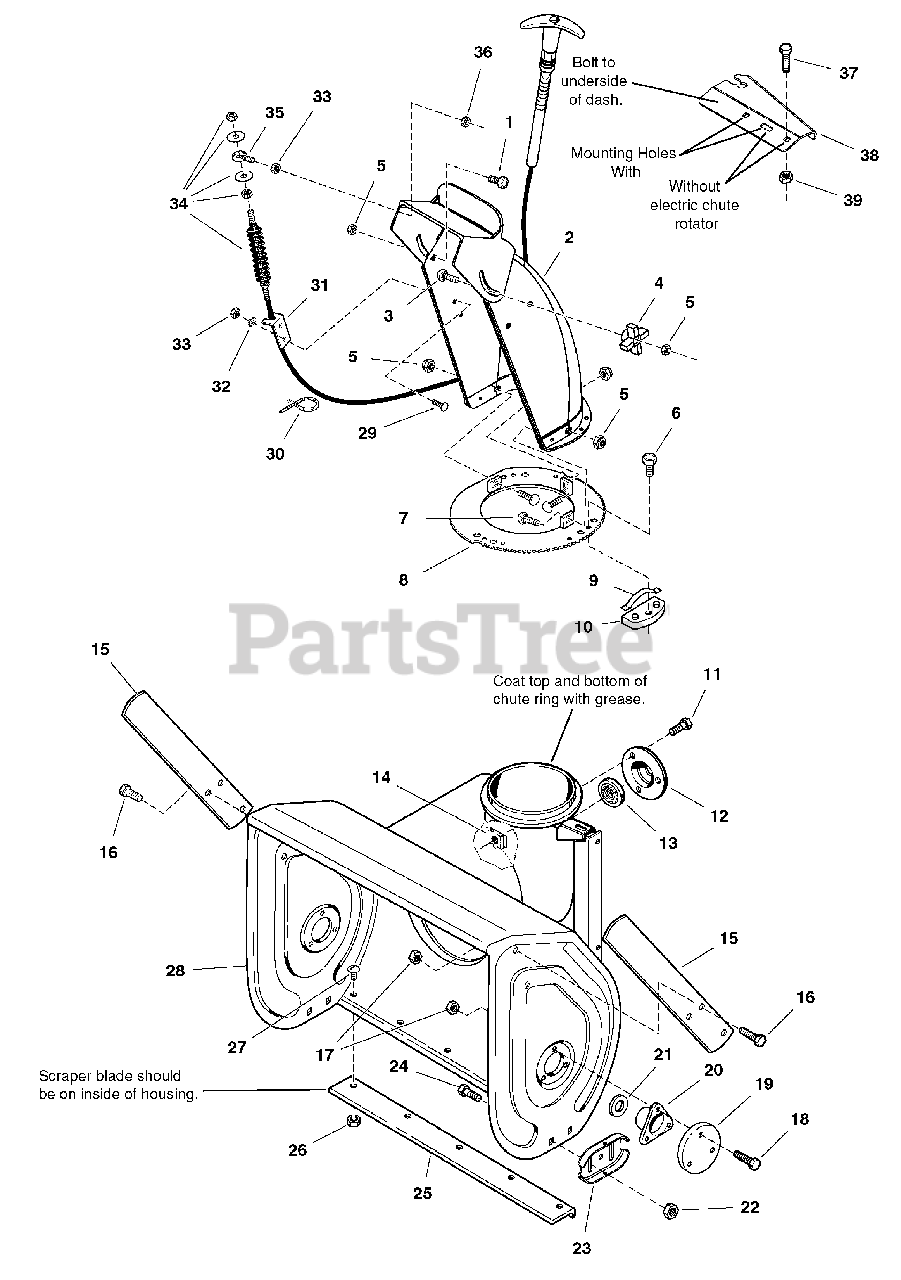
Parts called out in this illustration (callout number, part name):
1	CAPSCREW, Hex Head, 5/16-18 x 3/4 G5
2	CHUTE AND DEFLECTOR ASSEMBLY, w/Remote
2	CHUTE AND DEFLECTOR ASSEMBLY, Manual
3	BOLT, Carriage, Short Neck, 5/16-18 x 1
4	KNOB, Internal Thread, 5/16 (See Only 986714, 986717)
5	NUT, Hex Flange ESNA, 5/16-18
6	SCREW, Hex Washer Head Pastite, 10-14 x 5/8
7	CARRIAGE BOLT, 5/16-18 x 3/4 (See Only 986714, 986717)
8	RING AND TABS ASSEMBLY, Gear
9	SPRING, Flat
10	HOLD DOWN, Chute
11	CAPSCREW, Hex Head Whiz Lock, 5/16-18 x 5/8 G5
12	RETAINER, Bearing
13	BEARING, Ball
14	NUT, Retainer Speed, 5/16-18
15	CUTTER, Drift, 1/4" Thick, 20LG
16	CAPSCREW, Hex Head Taptite, 5/16-18 x 3/4 G5
17	NUT, Hex Keps, 5/16-18, Conical Washer
18	CAPSCREW, Hex Head 5/16-18 x 7/8 G5
19	CAP, Bearing, 3-3/4OD
20	BEARING, Flange
21	SPACER, Low
22	NUT, Hex Flange 3/8-16 ESNA
23	SKID SHOE, Reversible
24	CARRIAGE BOLT, 3/8-16 x 3/4 G5
25	BLADE, Scraper, 24"
25	BLADE, Scraper, 28"
25	BLADE, Scraper, 32"
26	NUT, Hex Flange, 5/16-18, Two-Way Lock GA
27	CARRIAGE BOLT, 5/16-18 x 5/8 G5
28	HOUSING AND IMPELLER ASSEMBLY, 24"
28	HOUSING AND IMPELLER ASSEMBLY, 28"
28	HOUSING AND IMPELLER ASSEMBLY, 32"
29	BOLT, Carriage, 1/4-20 x 5/8
30	TIE, Self Locking
31	MOUNT, Cable
32	LOCKWASHER, External Tooth, 1/4
33	NUT, Hex Whiz Lock, 1/4-20 NC-2B
34	CABLE, Remote Chute Deflector, 60"
35	EYEBOLT, 1/4-20 x 1-1/2 LG
36	NUT, Hex Lock ESNA Light, 1/4-20NC-3B
37	CAPSCREW, Hex Head 1/4-20 x 3/4 G5
38	SUPPORT, Cable Tubular Handles, 12GA
39	NUT, Hex KEPS, 1/4-20, Conical Washer
